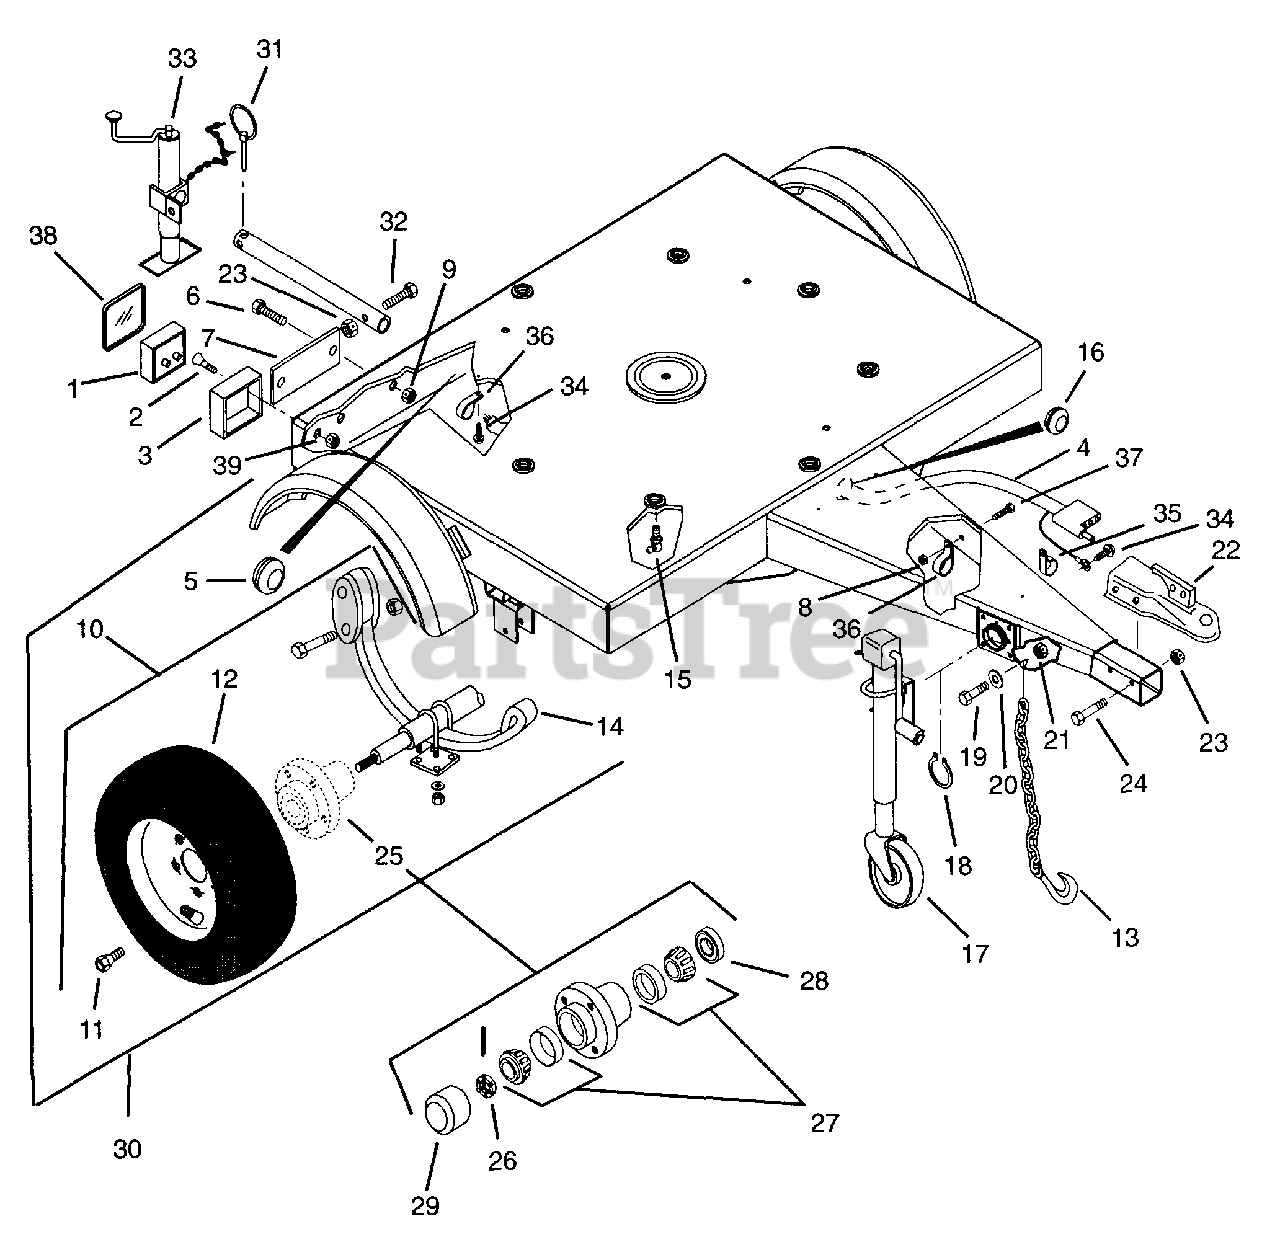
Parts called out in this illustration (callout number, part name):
1	Taillight-Left Hand
1	Taillight-Right Hand
2	Screw-Machine-Flat .25 X .75
3	Left Taillight Weldment
3	Right Taillight Weldment
4	Wire Harness
5	Grommet .188 X .375 ID
6	Screw-Machine-Hex Head 10-24 X .75
7	Reflector
8	Nut-Locking-Center .25-20
9	Nut-Locking-Nylon 10-24 w/Insert
10	Trailer Axle-Complete - Less Tire and Wheels
11	Bolt-Hex .50-20 x .75 x 1.62 Plated
12	Tire/Wheel Assembly
13	Safety Chain
14	Spring-Axle-Service Assembly
15	Fitting-Hydraulic Drive
16	Grommet .75 X 1.06 X 1.38
17	Jack Assembly
18	Ring-Retaining-External 2.500 X .078
19	Bolt-Hex .44-14 X 1.00 Grade 5
20	Washer-Flat-Steel .50 x 1.25 x .083
21	Nut-Locking-Center .44-14
22	Coupler-2" Ball Type
23	Nut-Locking-Center .50-13
24	Bolt-Hex .50-13 x 3.75 Grade 5
25	Hub
26	Nut-Slotted 1.0-14
27	Replacement Bearing Assembly
30	Trailer
31	Tube-Jack-Pivot
32	Bolt-Hex .50-13 x 3.00 Grade 5
33	Jack-2000 Lb x 12.75 Screw
34	Screw-Tapping .25 x .50 HWH
35	Clamp-Cushioned Steel
37	Bolt-Hex .25-20 x .75 Grade 5
38	Lens-Tail Light
39	Nut-Locking-Nylon .250-20
